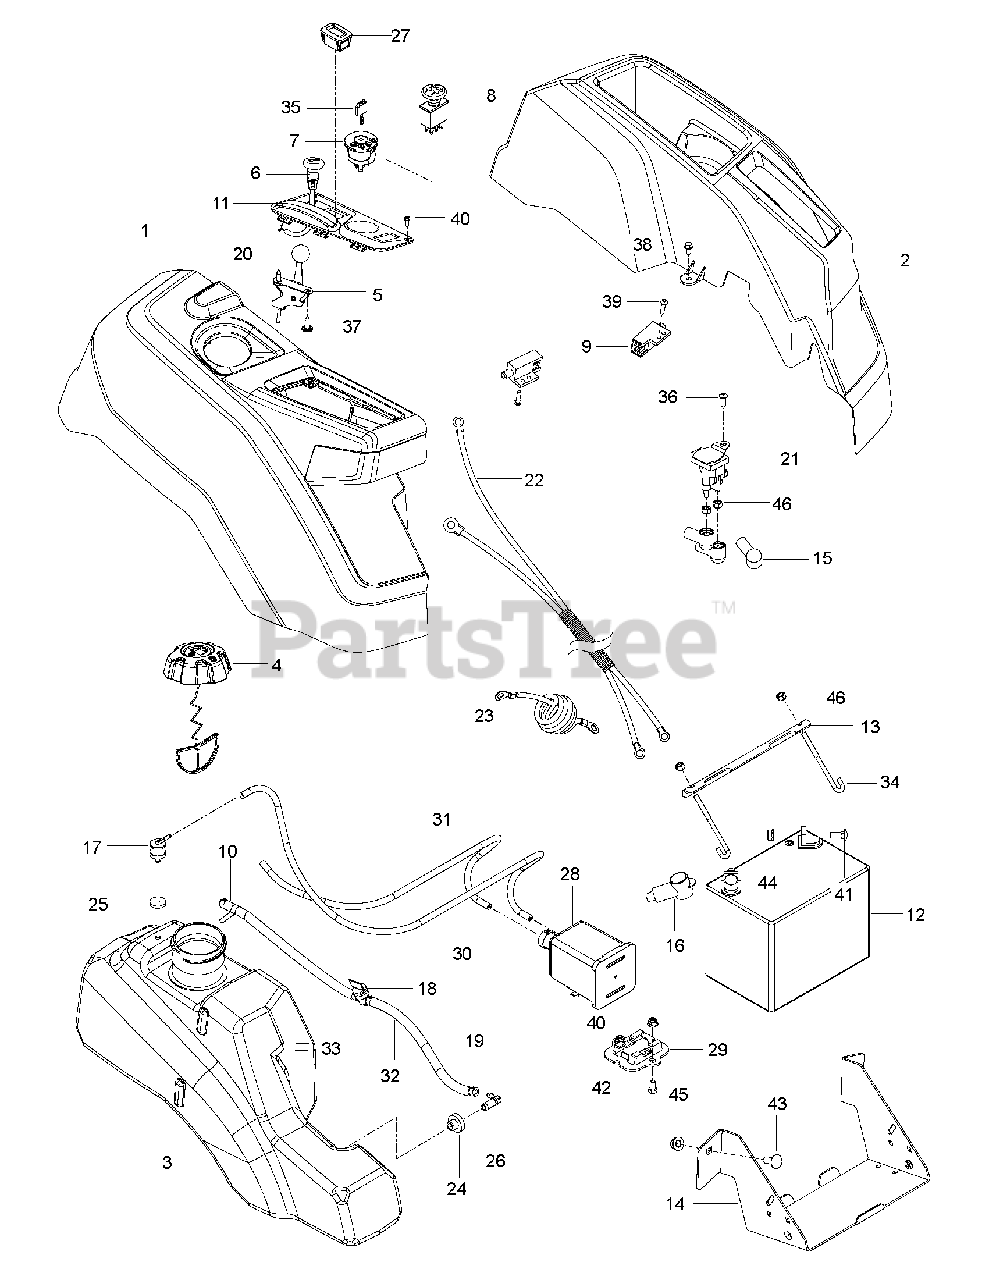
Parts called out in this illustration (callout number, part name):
1	CONSOLE.ASSY.RZ.REFRESH.RH
2	CONSOLE.LH.ASM
3	ASM.FUEL.TANK.LG.3".W/O SHIELD
4	CAP ASSY FUEL 3" GRAY
5	THROTTLE CABLE
6	CHOKE.PUSH-IN.STYLE
7	RP IGNITION SWITCH
8	RP SWITCH.PTO.TERMINAL.STD.RED
9	SWITCH.INTLK.RZ.RFRSH.BUTTON
10	FUEL.HOSE.SHUT.OFF.ASM.10".18"
11	CONTROL.PANEL.RZ.REFRESH.RH
12	BATTERY, 12 V 330 AMP
13	BRACKET.PNT.MOUNT.BATTERY.EDIP
14	BOX.PNT.BATTERY.RZ.EDIP
15	TERMINAL COVER
17	VALVE.FUEL.CHECK
18	FUEL VALVE
19	HOSE CLAMP
20	KNOB.ROUND.BALL.BLACK
21	SOLENOID.W/BRASS.PLUNGER
22	HARNESS.BTTRY.CABLE.RZ.REFRESH
23	CABLE BATTERY POS RZ
24	BUSHING OUTLET T
25	GROMMET.ROV.SENTEC
26	STEM FUEL TANK
27	GUAGE.SRVCMNDR.HRMTR.
28	CANNISTER, CARBON
29	BRACKET, CANISTER
30	HOSE.3/16".VAPOR.LINE.36"LGTH
31	HOSE.3/16".VAPOR.LINE.33"LGTH
32	HOSE.1/4".LOW.PERM.FUEL.LN.10"
33	Fuel Hose, 1/4" Low Permeation Fuel Line 18"
34	HOOK.J.BATTERY
35	KEY MLD GEN DELTA
36	SCR 1/4-20 X 5/8 BTN SKT HD ZD
37	SCREW.PAN.HEAD.#10
38	SCREW
39	SCREW.BUTTONHD.10-24X1/2.(2 2)
40	SCREW 6-19X.437
41	BOLT 5/16-18 X3/4 ZN/YEL GR 5
42	HCS 5/16-18 X 5/8 GR 5 ZD
43	RHSNB 3/8C X 1
44	5/16-18 NYLOC FLANGE NUT
45	NUT 3/8-16 HEX FLG NYLOC ZD
46	RP_NUT 1/4-20 NYLOC
